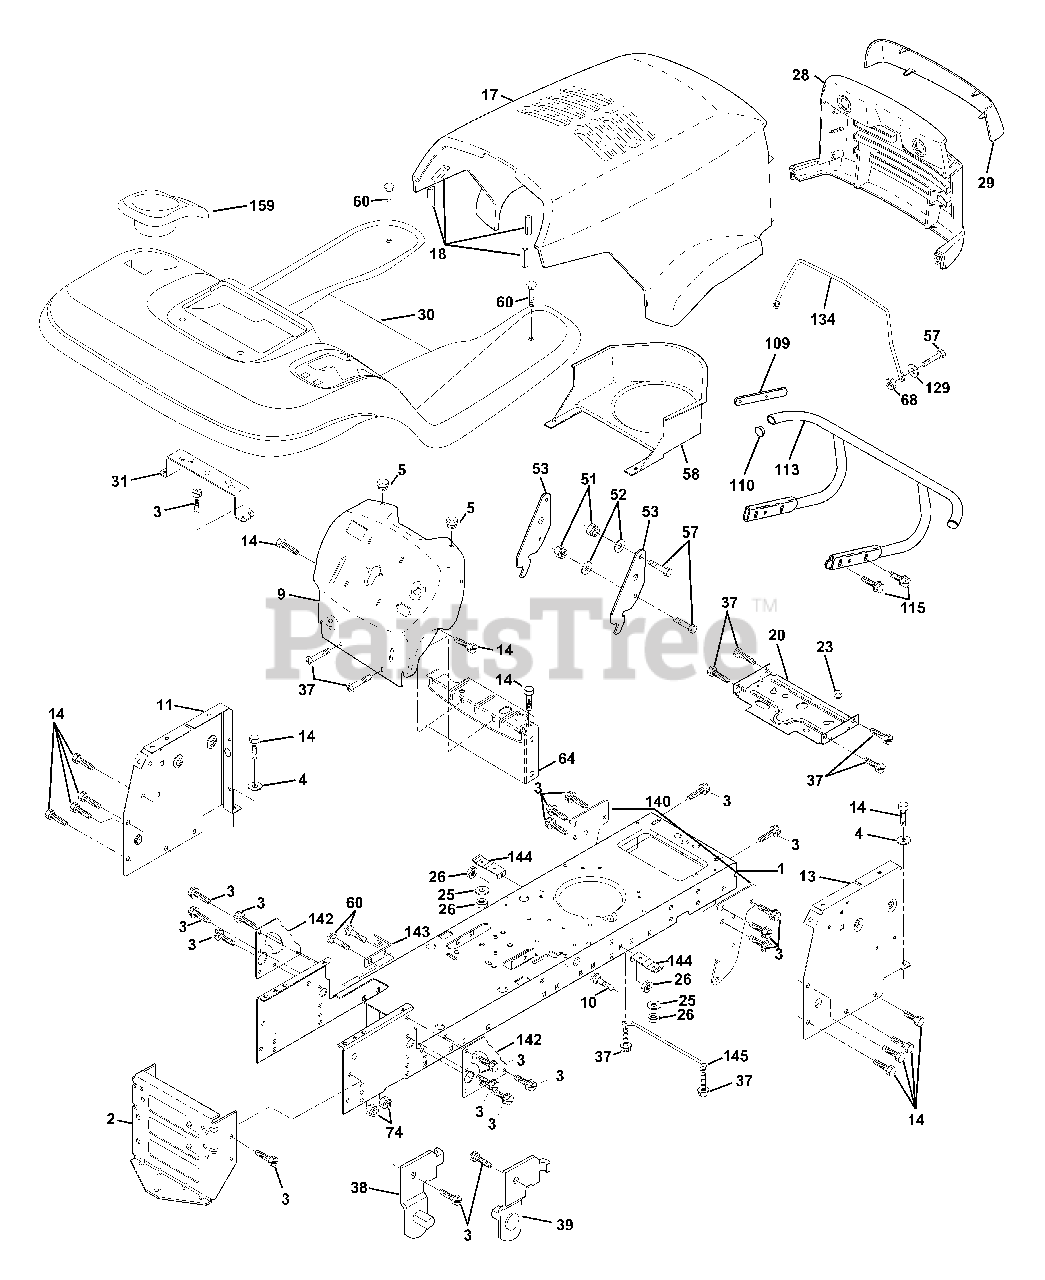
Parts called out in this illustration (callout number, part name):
1	Chassis Weldment
2	Drawbar, Stretch
3	Screw Thdrol 3/8-16x3/4 Ty-tt
4	Washer 13/32 x 3/4 x 16 Ga.
5	Bumper Hood/Dash
9	Dash Slkscr.Plm.E.A.Hm.Nc.Sym
10	Bolt Carriage 3/8-16 x 1
11	Panel Dash Lh
13	Panel Dash Rh
14	Screw Thdrol 3/8-16x1/2 Ty-tt
17	Hood LT/PL Husqvarna
18	Bumper Hood
20	Plate Mtg Battery Fuel Tank Fr
25	Washer 13/32 X 13/16 X 12 Ga
26	Nut Lock Hex W/Ins 3/8-16 Unc
28	Grille LT/PL Husqvarna
29	Lens LT/PL Husqvarna
30	Fender Footrest STLT Pnt
31	Bracket Support Fender
37	Screw Thdrol 6/16-18 x 1/2 TYT
38	Bracket, Asm. Pivot, L.H., Mower
39	Bracket, Asm. Pivot, R.H., Mower
51	Nut Lock Hex W/Ins 1/4-20
52	Washer 9/32 x 7/8 x 16 Ga.
53	Bracket Pnt. Pick off LT/PL Husqvarna
57	Bolt Hex 1/4-20 x 3/4
58	Air Duct Engine P/L
60	Bolt Rdhd Sqnk 3/8-16unc x 3/4
64	Dash Lower STLT
68	Nut Keps Hex 1/4-20unc
74	Nut Crownlock 3/8-16 UNC
109	Bracket Extension Bumper
110	Plug Plastic
113	Bumper Asm.
115	Screw Thdrol 3/8-16 x 1-1/4
129	Washer 9/32 x 5/8 x 16 Ga.
134	Rod Support Hood LT/PL Husq.
140	Bracket Suspension Front
142	Plate Reinforcement STLT
143	Bracket Swaybar Chassis
144	Bracket Pnt Footrest STLT
145	Rod Pivot Chassis/Hood
159	Cupholder STLT Grey
